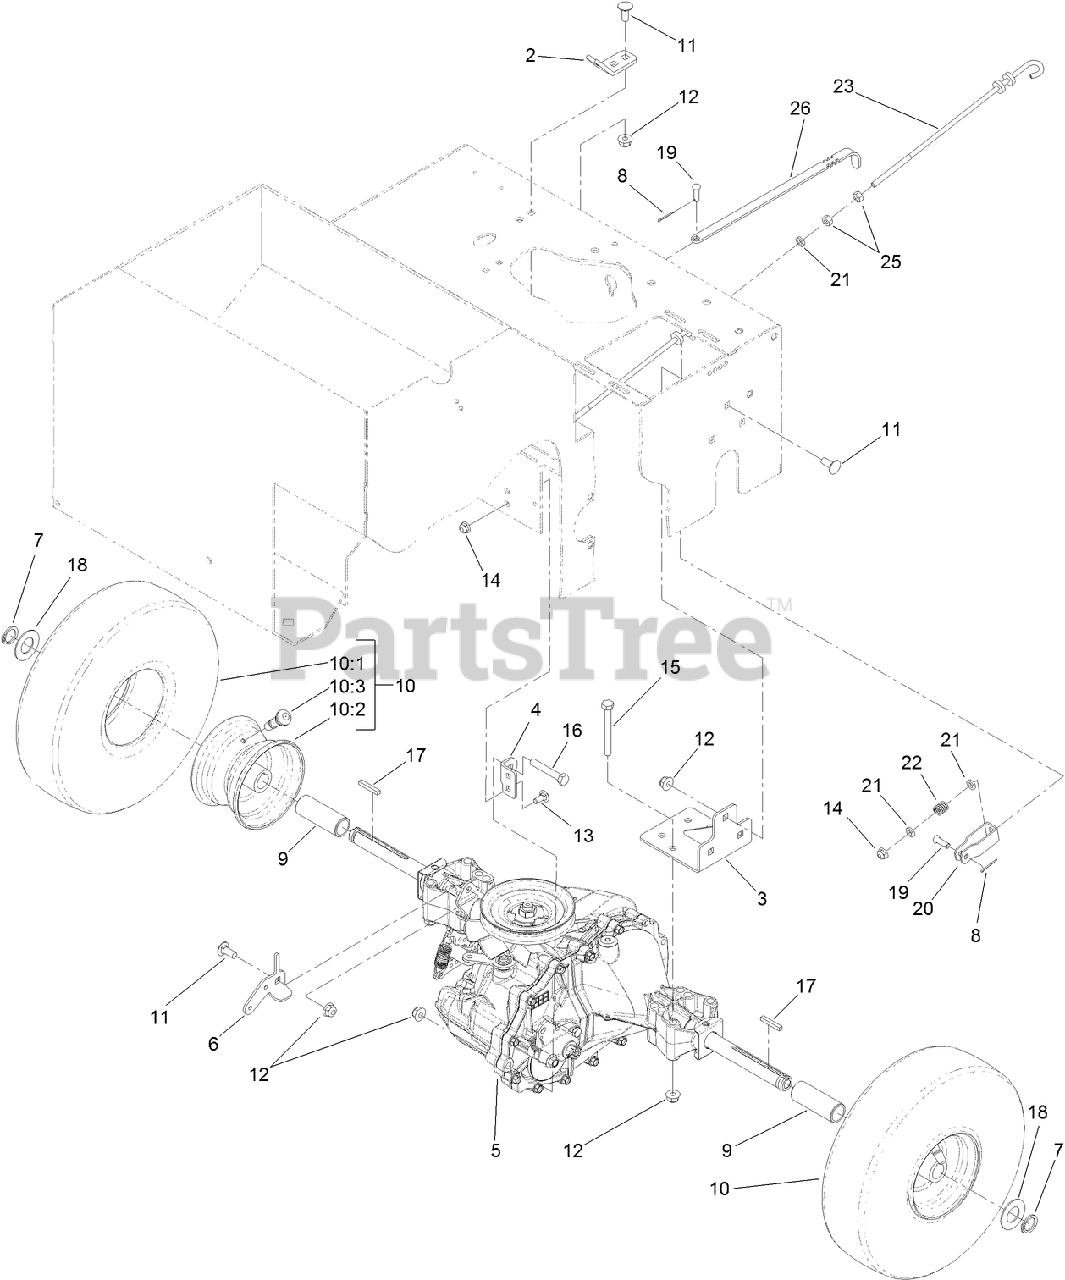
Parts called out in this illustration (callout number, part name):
2	BRACKET-CABLE
3	BRACKET-AXLE
4	BRACKET-TRANSAXLE, TORQUE
5	TRANSAXLE ASM
6	BRACKET-TRANSAXLE
7	RING-RETAINING
8	PIN-COTTER
9	SPACER
10	WHEEL AND TIRE ASM
10:2	RIM-GRAY
10:3	VALVE
11	SCREW-CARR
12	NUT-HF, NI
13	SCREW-CARR
14	NUT-HF
15	SCREW-HH
16	SCREW-HH
17	KEY-SQUARE
18	WASHER
19	PIN-CLEVIS
20	CLEVIS
21	SPACER-PLATE, PIVOT
22	SPRING-COMPRESSION
23	ROD-BRAKE
25	NUT-HEX
26	LEVER-BYPASS
